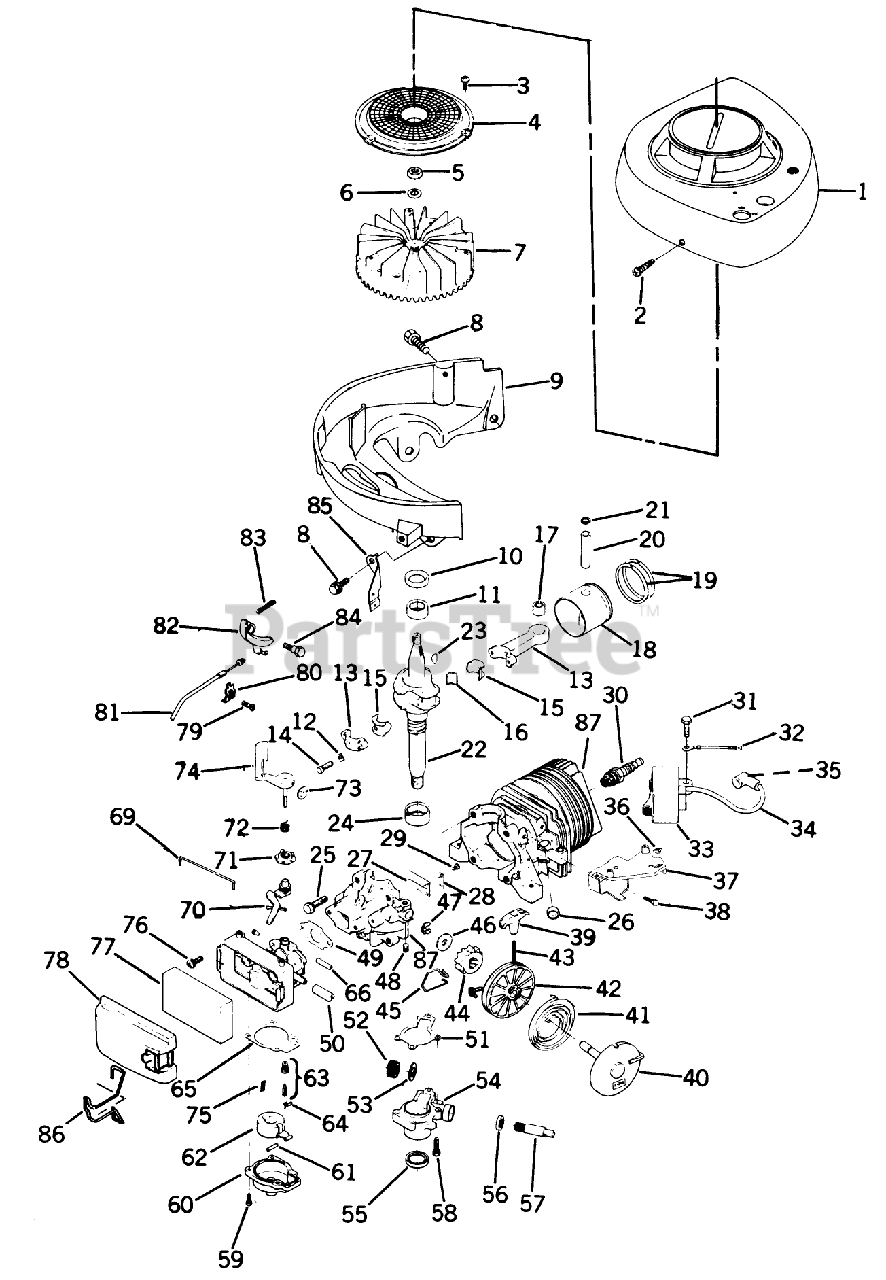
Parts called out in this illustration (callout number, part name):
2	SCREW F
3	SCREW F
5	NUT
8	SCREW-SEMS
11	BEARING V
14	SCREW
15	LINER ASM
17	BEARING AY F
21	RING-RETAINING
23	KEY
24	BEARING S
25	SCREW S
26	PLUG-CORE VF
28	PLATE-BACKUP, REED
34	HT LEAD&COVER XEV
36	NUT-CLIP
37	BRACKET S
39	HANDLE STARTER S
41	SPRING S
45	SPRING F
46	WASHER S
48	SET SCREW
49	GASKET CARB S
51	GASKET S
52	GEAR, DR SHAFT S
53	THRUST WASHER
56	SEAL S
59	SCREW-HH
66	TUBING PRIMER S
68	F-SCREW CARB
69	RETAINER
70	LEVER
71	ADJUSTMENT COLLAR
72	SPRING
73	DISC S
76	SCREW
80	CLIP S
82	LEVER LOCKOUT S
84	BOLT S
86	RETAINER-COVER, FILTER
